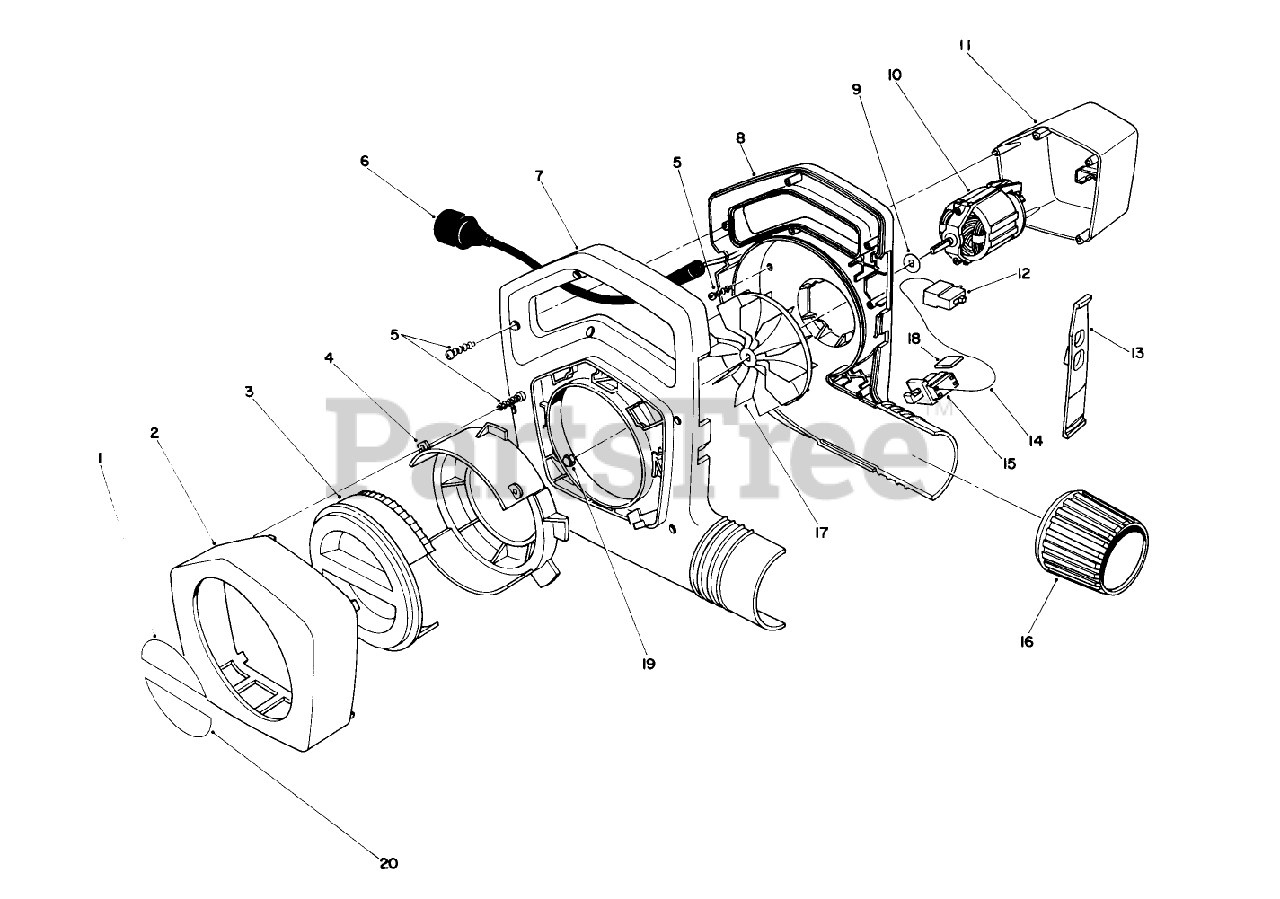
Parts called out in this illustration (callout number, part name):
10	MOTOR, BLOWER (450/550)
15	SWITCH-INTERLOCK
19	NUT-ACORN
